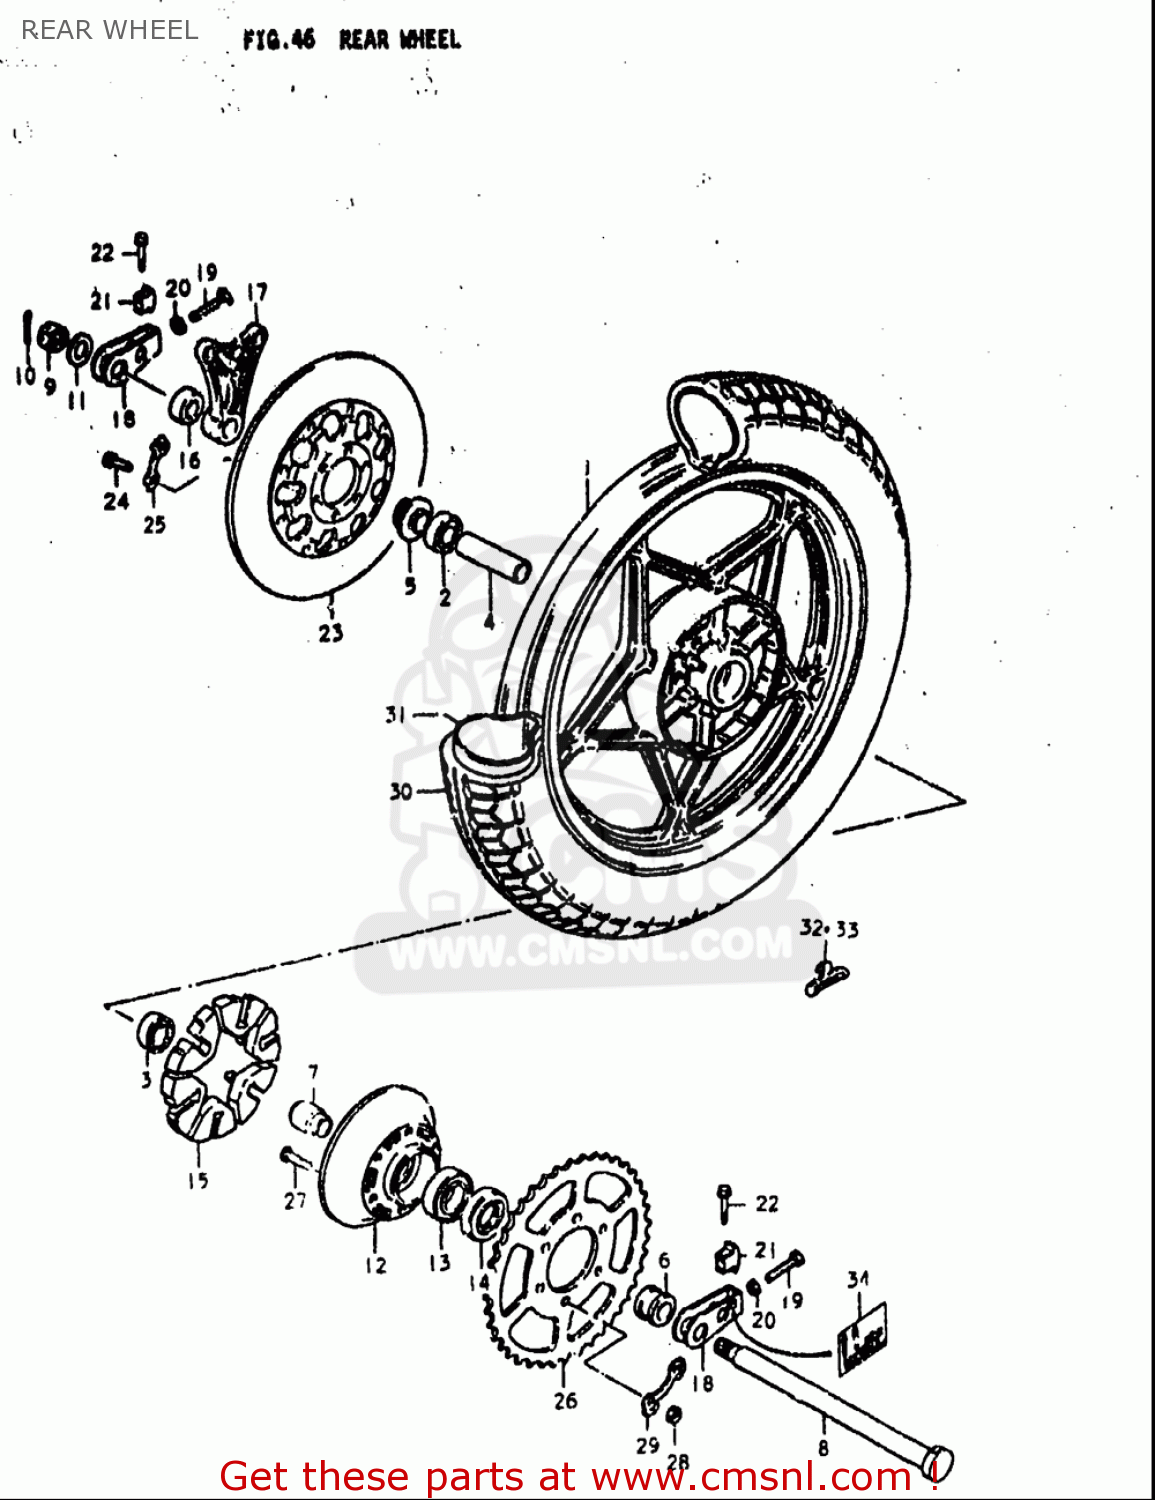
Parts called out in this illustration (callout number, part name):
2	BEARING WHEEL REAR(20X47X14)
3	BEARING(20X47X14)
4	SPACER(20.5X28X88)
5	SPACER,RR AXLE,R
6	SPACER(20X33X28.3)
7	SPACER,REAR HUB BEARING
8	AXLE,REAR
9	NUT 18MM
10	PIN
11	WASHER(19X34X4)
12	DRUM,RR SPROCKET MOUNTING
13	BEARING(25X62X17)
14	SEAL,OIL(33X62X7)
15	ABSORBER,RR HUB SHOCK
16	SPACER(20X38X12)
17	BRACKET,RR,CALIPER
18	ADJUSTER,CHAIN
19	BOLT 8X50
20	NUT
21	SUPPORTER,CHAIN ADJUST
23	DISC,BRAKE
24	BOLT(8X30)
25	WASHER
26	SPROCKET,RR(NT:42)
27	BOLT(10X35.5)
28	NUT
29	WASHER
30	TIRE 4.50V17
32	BALANCER,WHEEL
34	LABEL,CHAIN WEAR INDICATOR
